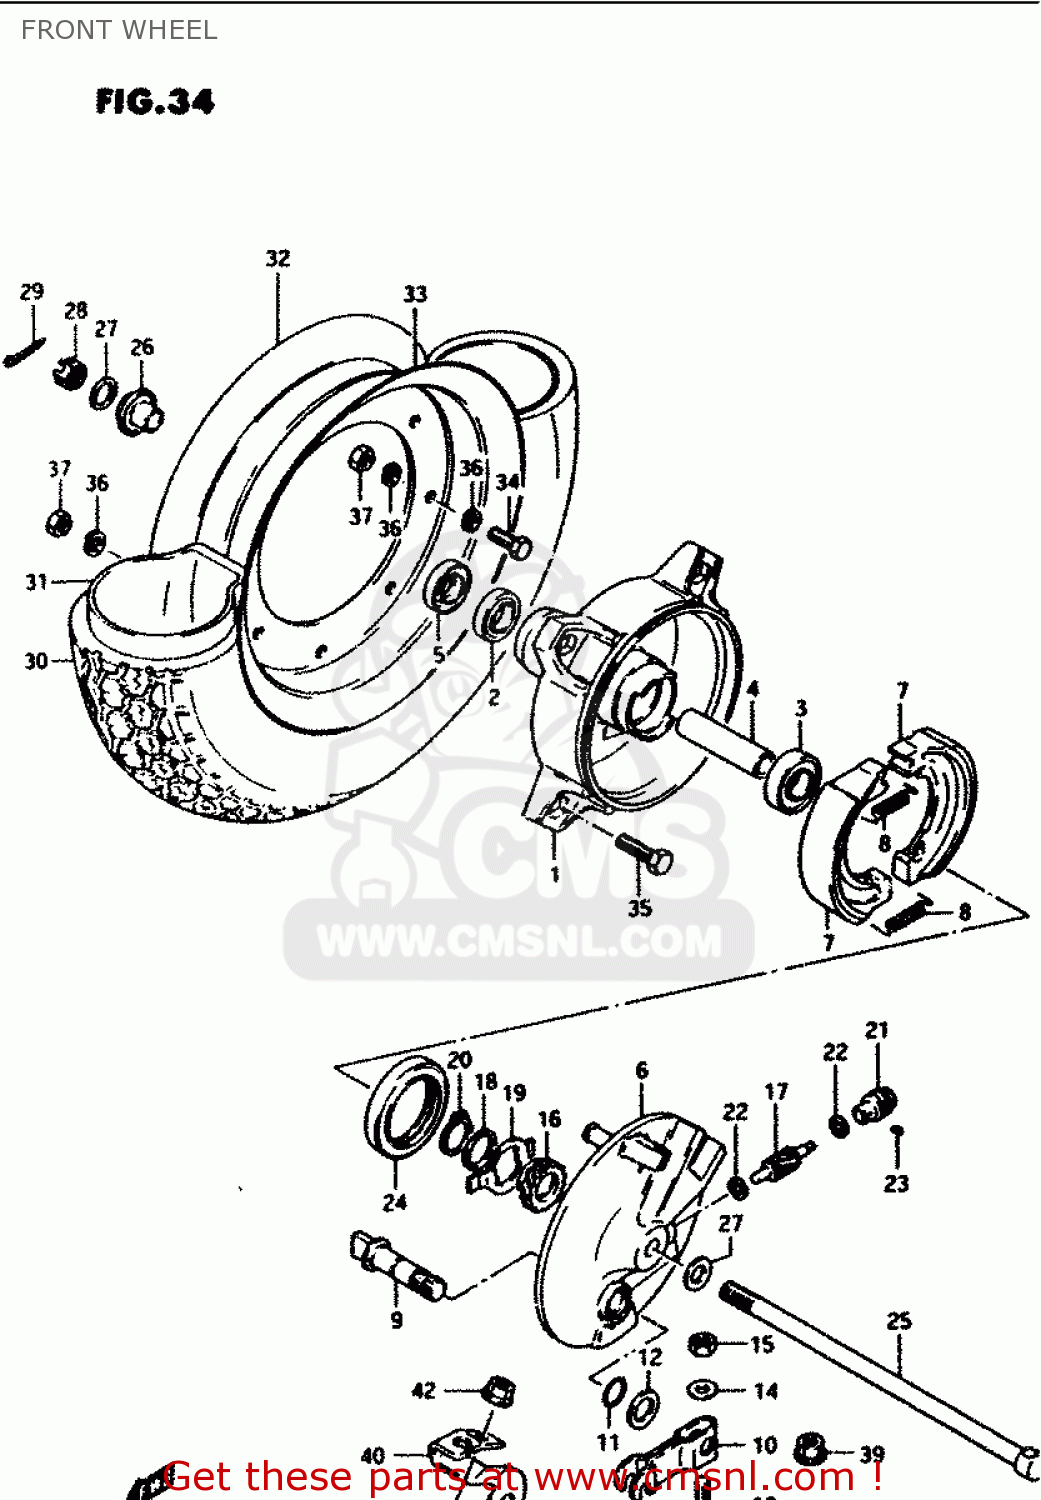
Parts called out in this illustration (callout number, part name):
1	HUB,FR WHEEL
2	BEARING
3	BEARING
4	SPACER(10.2X16X66)
5	SEAL,OIL(15X31X5)
6	PANEL, FRONT BRAKE ANCHOR
7	SHOE,BRAKE
8	SPRING(L:35.8)
9	CAM,FRONT BRAKE
10	LEVER, CAM
11	O-RING (D:2.4 ID:13.8)
12	WASHER (14.5X22X1.6)
13	BOLT(6X33)
14	WASHER
15	NUT
16	GEAR,SPEEDOMETER(NT:18)
17	PINION,SPEEDOMETER(NT:11)
18	WASHER(18.5X24X1)
19	DRIVER,SPEEDOMETER GEAR
20	CLIP
21	BUSH,METER GEAR OUTER
22	WASHER (5.1X9X0.4)
23	SCREW
24	OIL SEAL (43X58X7)
25	AXLE, FRONT
26	SPACER,FRONT AXLE,RIGHT
27	WASHER
28	NUT
29	PIN 20X20
30	TIRE, REAR (3.50-8) IRC
31	TUBE ASSY,WHL I
32	RIM,WHEEL,R(8X2.50C)
33	RIM,WHEEL,L
34	BOLT,8X16
35	BOLT
36	WASHER,LOCK
37	NUT
38	BOLT(6X32)
39	NUT
40	STOPPER, BRAKE CABLE
41	BOLT
42	NUT
